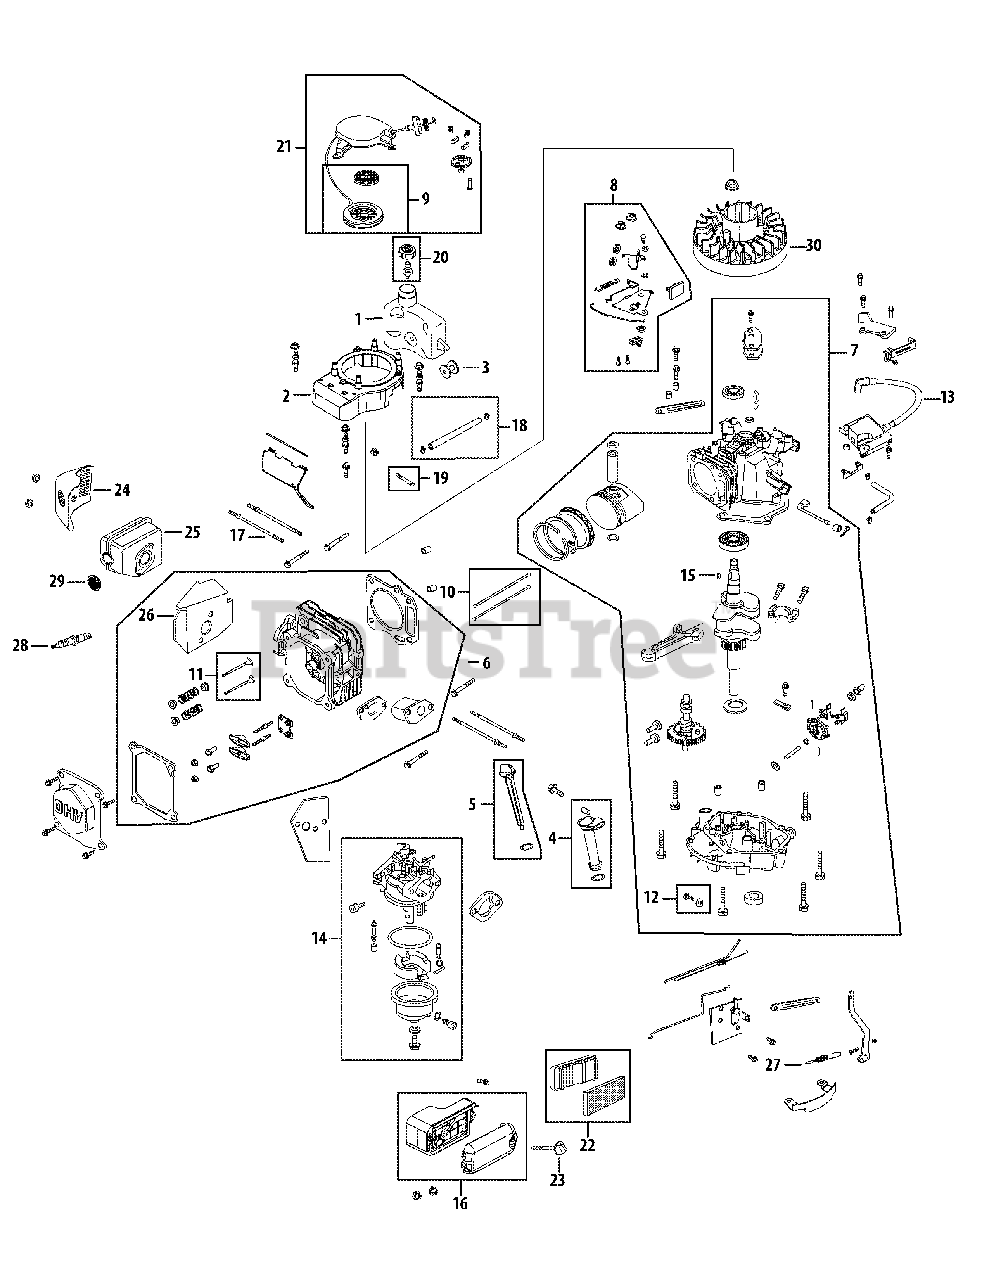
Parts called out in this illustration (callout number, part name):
1	Fuel Tank
2	Flywheel Shroud
3	Rubber Fuel Tank Mounting Washer
4	Oil Filler Tube Assembly
5	Dipstick Assembly
6	Cylinder Head Assembly
7	Short Block Assembly
8	Stop Switch and Brake Assembly
9	Recoil Spring and Pulley Assembly
10	Push Rod Kit
12	Oil Drain Plug and Washer Assembly
13	Ignition Coil
14	Carburetor Assembly
15	Flywheel Key
16	Air Cleaner Housing Assembly Complete
17	Muffler Stud Assembly
18	Fuel Line Kit - Inc. hoses & clamps
19	Fuel Filter
20	Fuel Cap Assembly
21	Recoil Starter Assembly
22	Air Cleaner Kit
23	Air Cleaner Thumb Screw
24	Muffler Guard
26	Muffler Gasket /Heat Shield
27	Governor Return Spring
28	Spark Plug
29	Spark Arrestor
